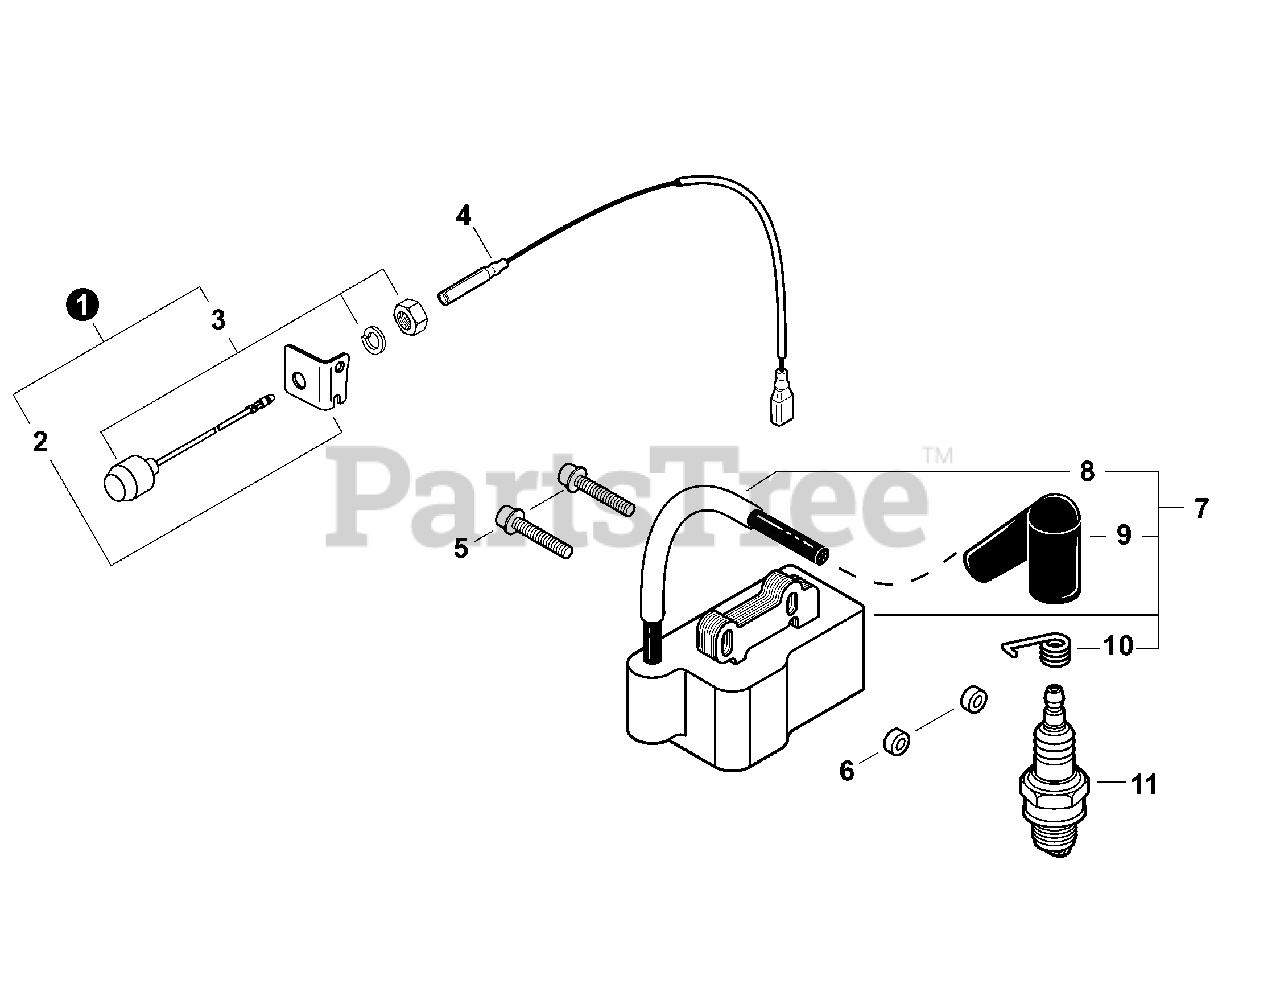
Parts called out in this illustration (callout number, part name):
1	SWITCH ASSY, STOP W/BRACKET
2	BRACKET
3	SWITCH ASSY, STOP
4	LEAD, IGNITION L=220mm
5	BOLT M4×26
6	INSULATOR 4.2×11×6
7	COIL ASSY, IGNITION
8	SLEEVE, INSULATOR
9	CAP, SPARK PLUG
10	TERMINAL, SPARK PLUG
11	SPARK PLUG - CMR5H
